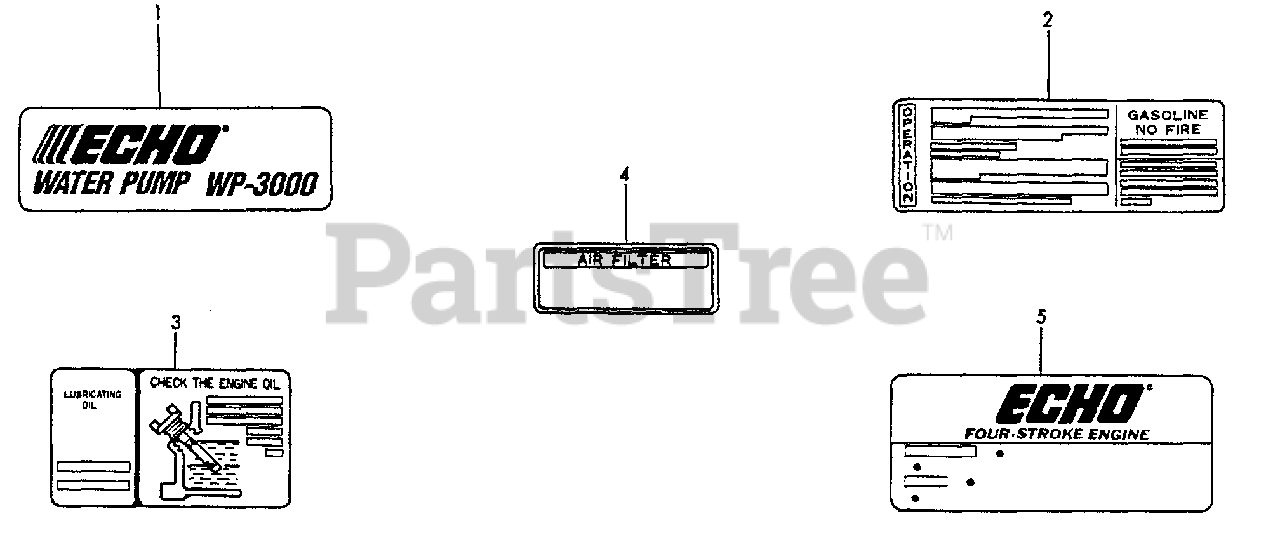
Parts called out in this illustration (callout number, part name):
1	LABEL - MODEL WP3000
2	LABEL - OPERATION
3	LABEL - OIL
4	LABEL - AIR CLEANER
5	LABEL - ECHO
